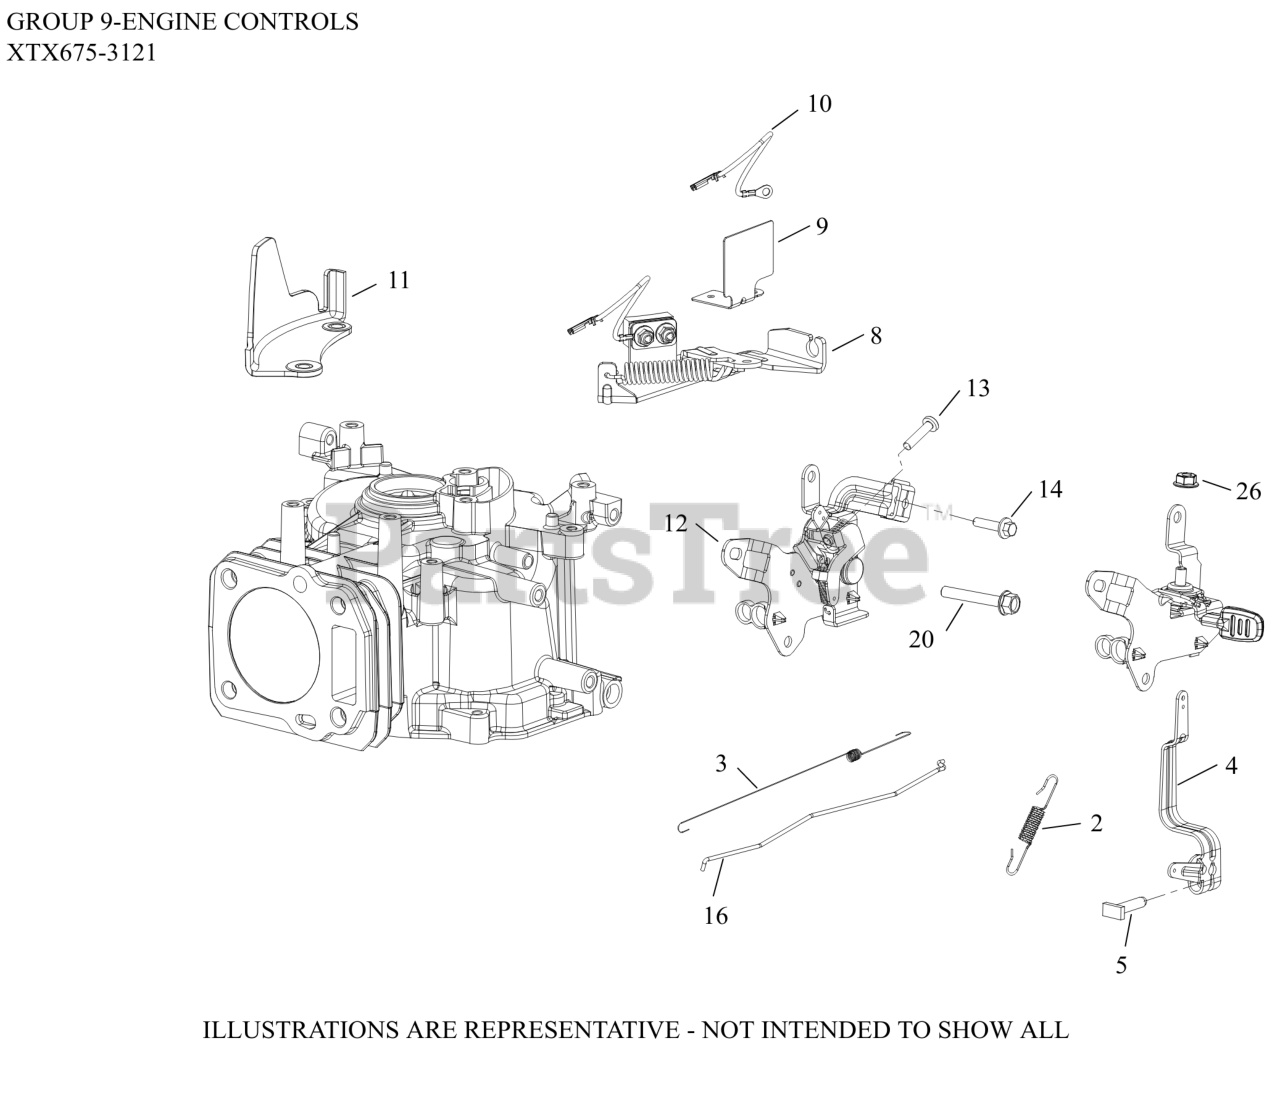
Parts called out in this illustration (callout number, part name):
2	SPRING, GOV (2800-3300 RPM)
3	SPRING, LINKAGE
5	SCREW, RECTANGLE HEAD (M6)
8	BRAKE ASSEMBLY
9	GUARD, BRAKE - USE 14 314 30-S
10	LEAD, KILL (BRAKE TO IGN. MODULE)
11	GUARD, FINGER
12	CONTROL ASSEMBLY (VAR. SPEED)
13	SCREW, #25 6-LOBE PAN HD (M5)
14	SCREW, (M5) HEX FLANGE
16	LINKAGE, GOVERNOR-(#1407927S)
20	SCREW, HEX FLANGE (M6)
26	NUT, HEX FLANGE LOCK (M6)
34	LEVER, GOVERNOR
